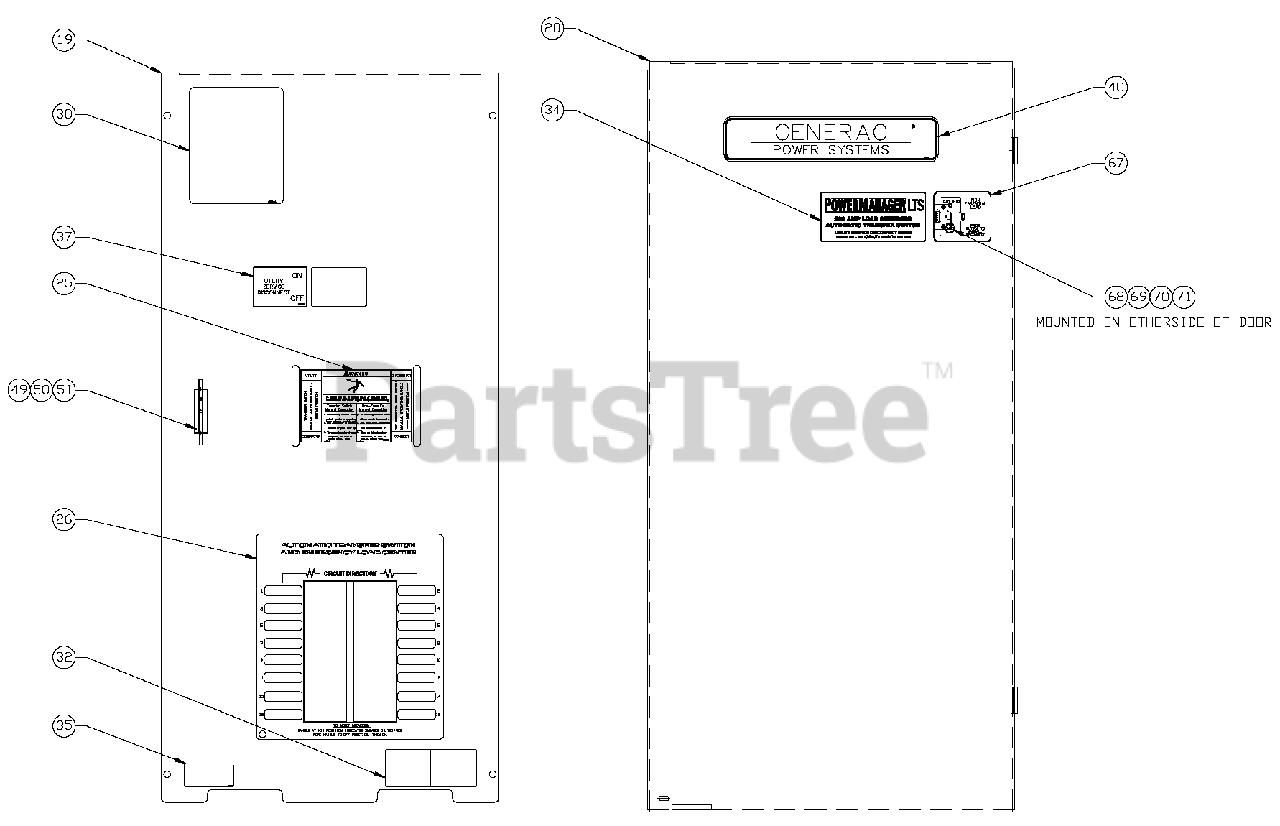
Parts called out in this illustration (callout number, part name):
19	INSIDE COVER LOAD SHED
20	COVER LOAD SHED ENCLOSURE
25	DECAL, TRANSFER SWITCH DATA 200
26	DECAL, WARN MANUAL OPER HANDLE
30	DECAL, CUSTOMER CONNECTION
32	DECAL, GROUNDING LUG
34	DECAL, UL PANELBOARD
35	DECAL, LIVE CIRCUIT ENG/FRN/SPN
37	DECAL, UTILITY SERVICE DISCONNECT
40	DECAL TRANSFER SWITCH RTS
49	BRACKET, ARM EXTENDER
50	RIVET POP .156 X .362 AL
51	ARM EXTENDER PIN
67	KEYPAD, LOAD SHED
68	ASSY PCB INTFC LOAD SHED KEYPD
69	NUT HEX LOCK M4-0.7 SS NYL INS
70	SPACER M4/# 8 X 5/16 X 1/4 NYL
71	CABLE, KEYPAD INTERFACE
